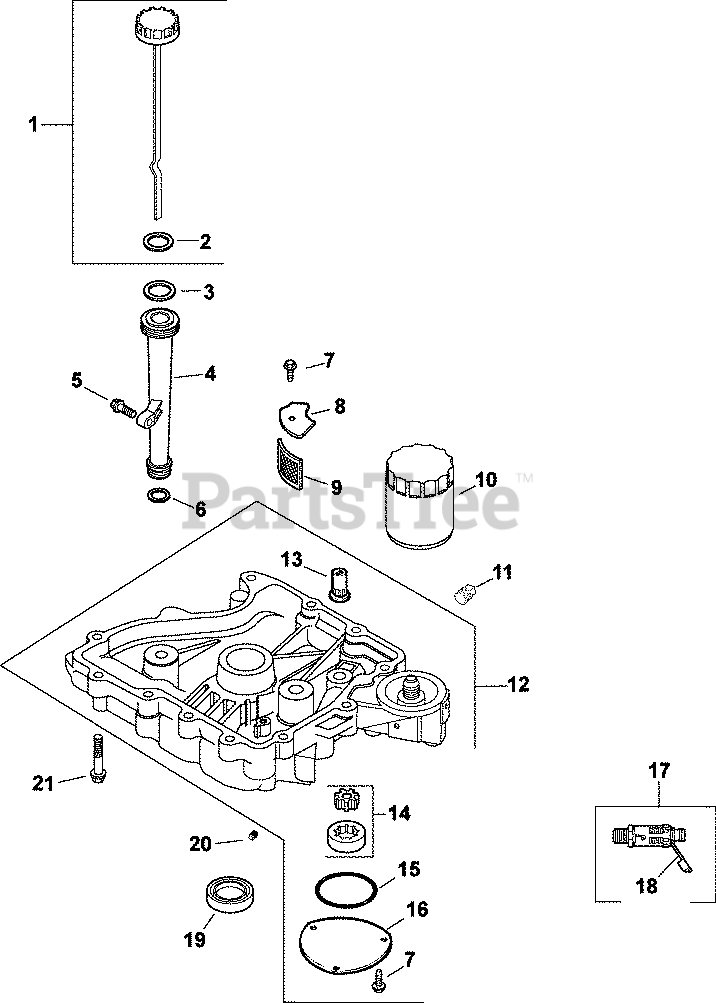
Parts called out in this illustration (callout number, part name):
1	DIPSTICK/CAP ASSY (BLACK)
2	O-RING, DIPSTICK
3	O-RING, UPPER OIL FILL TUBE
4	TUBE, OIL FILL USE 25 123 07-S
5	SCREW,FLG THD FRM M6X1.0X25-(#25086395S)
6	OIL FILTER
7	SCREW,FLG THD FRM M5X0.8X16-(#25086398S)
9	SCREEN, OIL-USE 24 162 26-S
10	OIL FILTER
11	PLUG, SQ HD PIPE 3/8"
12	PAN, OIL
13	VALVE, OIL PRESSURE RELIEF
14	PUMP ASSEMBLY, OIL - DISCONTINUED
15	O-RING (2.5" DIA)
16	COVER, OIL PUMP
17	KIT, OIL DRAIN VALVE
18	CAP, OIL DRAIN VALVE
19	SEAL, OIL
20	PLUG, PIPE 1/8 NPTF-SQ.HD.
21	SCREW, FLG M8X1.25X45
